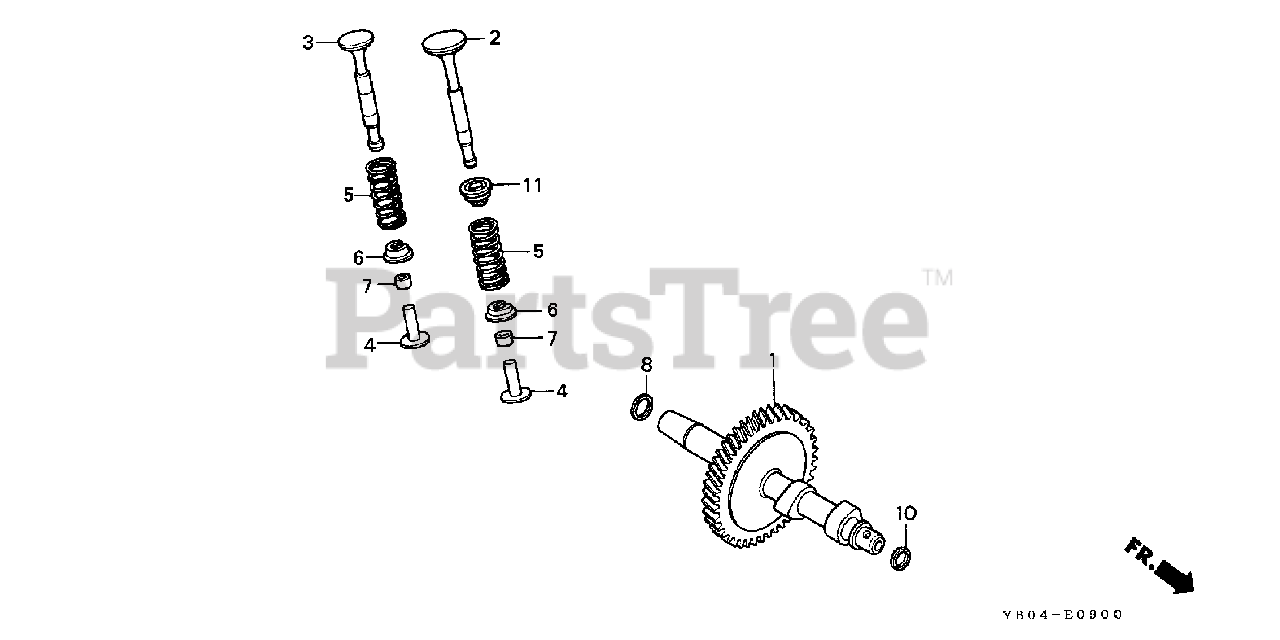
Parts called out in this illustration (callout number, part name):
2	VALVE, IN.
3	VALVE, EX.
4	LIFTER, VALVE
5	SPRING, VALVE
6	RETAINER, VALVE SPRING
7	ADJUSTER, TAPPET CLEARANCE (3.15)
7	ADJUSTER, TAPPET CLEARANCE (3.25)
7	ADJUSTER, TAPPET CLEARANCE (3.34)
7	ADJUSTER, TAPPET CLEARANCE (3.43)
7	ADJUSTER, TAPPET CLEARANCE (3.52)
7	ADJUSTER, TAPPET CLEARANCE (3.61)
7	ADJUSTER, TAPPET CLEARANCE (3.72)
7	ADJUSTER, TAPPET CLEARANCE (3.82)
8	WASHER (10MM)
10	WASHER, THRUST (9.9MM)
